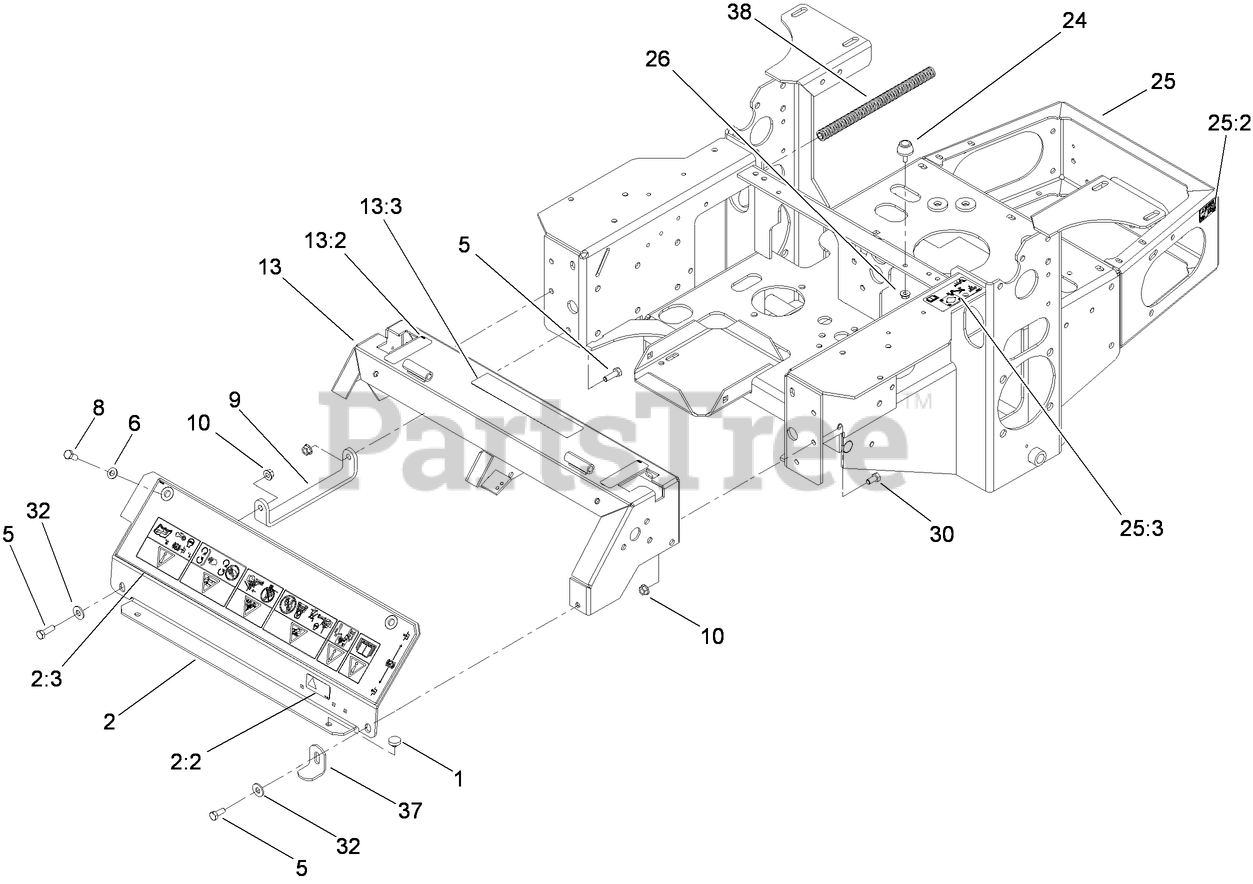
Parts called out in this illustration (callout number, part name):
1	BUMPER
2	PANEL ASM
2:2	DECAL-PROTECTION, EAR
2:3	DECAL-PANEL, FRONT
5	SCREW-HH
6	WASHER-PLAIN
8	SCREW-HH
9	BRACKET-PANEL, INSTRUMENT
10	NUT-HF
13	CONSOLE
13:2	DECAL-CONTROL, MOTION
13:3	DECAL-BATTERY
24	BUMPER-RUBBER
25	MAIN FRAME ASM
25:2	DECAL-WARNING
25:3	Decal-Release, Drive
26	NUT-HF
30	SCREW-HH
32	WASHER-FLAT
37	STOP-COVER
38	CONDUIT-CONVOLUTED, SPLIT
